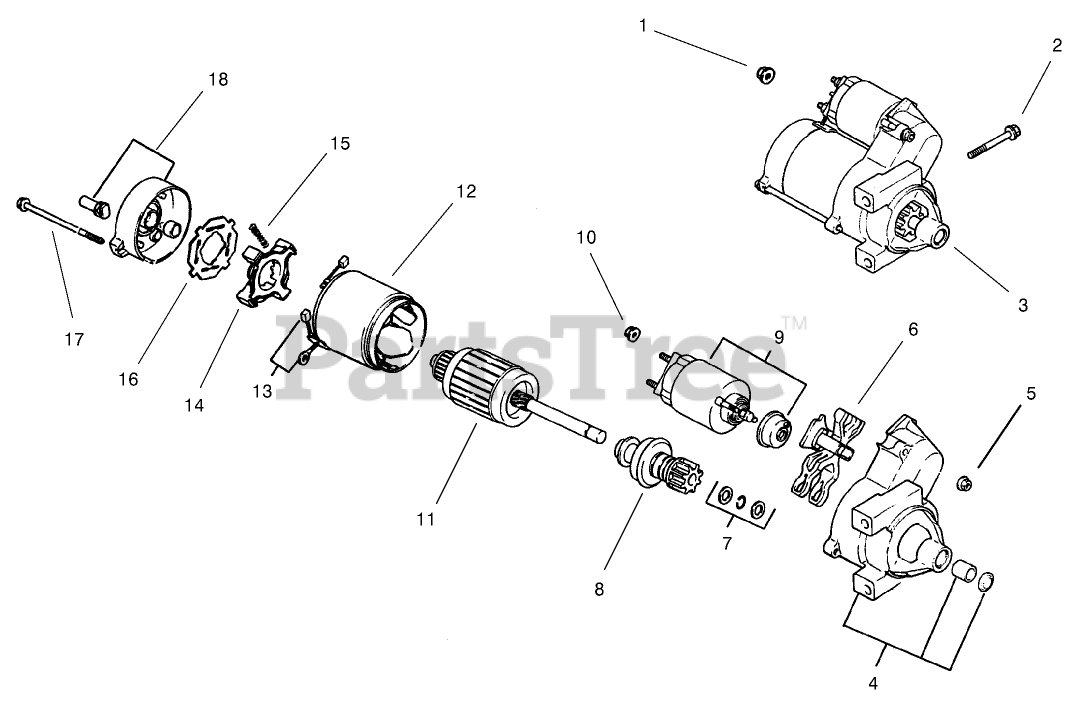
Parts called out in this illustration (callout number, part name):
1	Nut
2	Screw M8x1.25x80 (Only On: 72103, 72083)
3	Starter-Solenoid Shift (Incl. Ref. #4-20)
4	Cap-Drive End
5	Nut Starter
6	Lever Starter Drive
7	Washer
8	Drive-Pinion
9	Solenoid
10	Nut
11	Armature-Starter
12	Frame
13	Kit-Brush (Incl. Ref. # 16)
14	Holder-Brush
15	Spring-Brush
16	Insulator
17	Bolt
18	Commutator-End Cap
